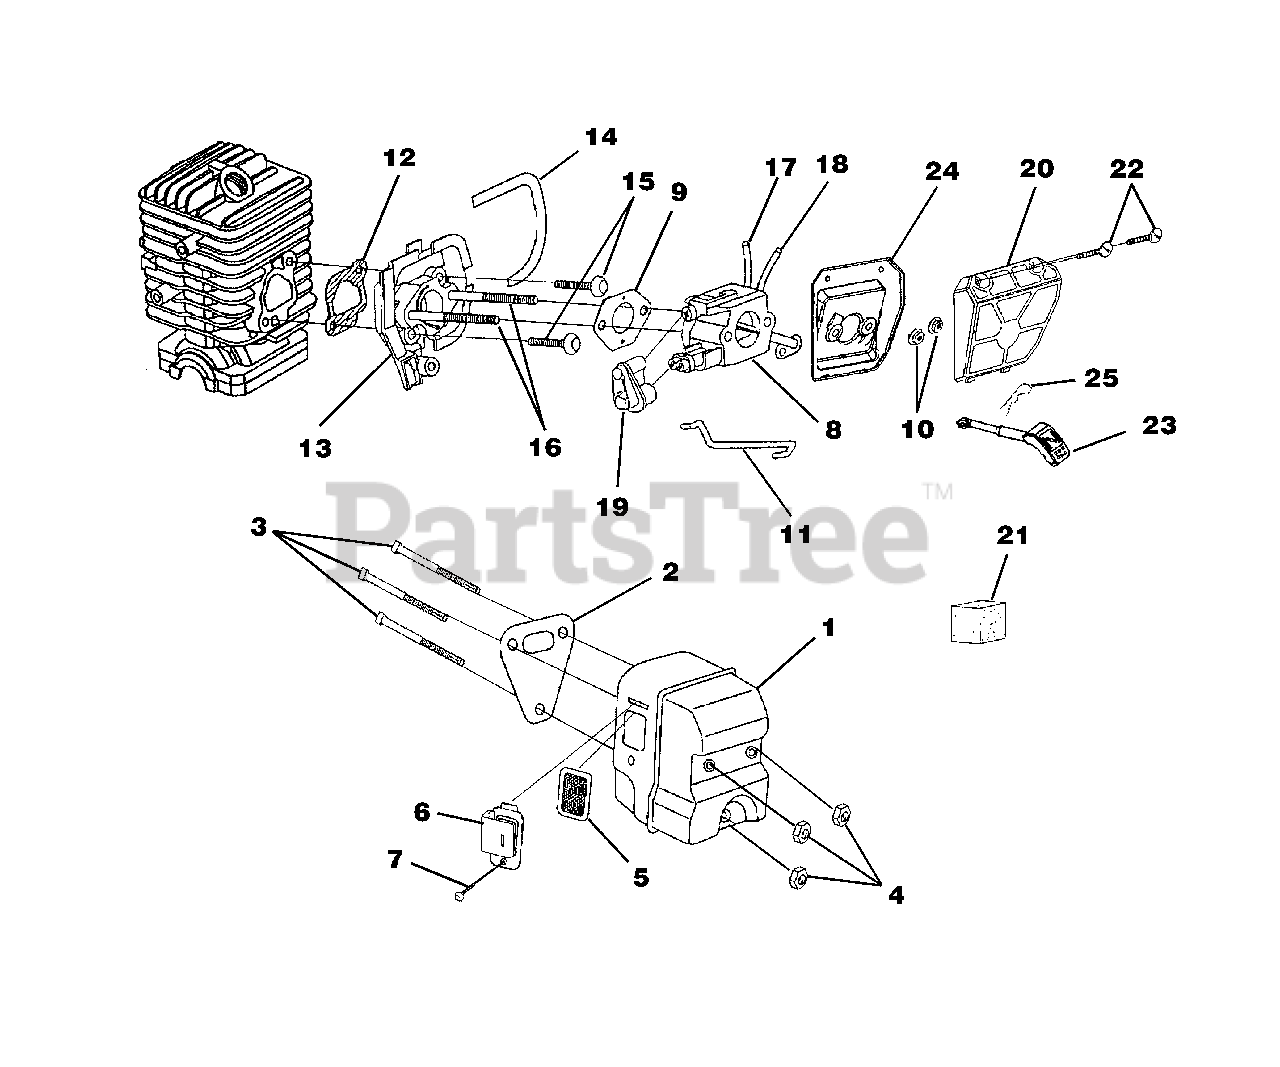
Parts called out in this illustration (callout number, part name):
1	Muffler Kit
2	Muffler Gasket
3	Screw-Square Hd.
4	Nut-Locking Hex (10-32)
5	Screen, Spark
6	Deflector, Muffler
7	Screw (8-32 x .312)
8	Carburetor Assembly
9	Carburetor Gasket
10	Flange Nut (10-24)
11	Throttle Wire
12	Gasket, Heat Dam
13	Heat Dam
14	Seal, Heat Dam
15	Screw, Truss Hd. Taptite (10-24 x 7/8")
16	Screw, Carburetor
17	Fuel Line (Tank to Carburetor 8 1/2")
18	Fuel Line (Carburetor to Purge Bulb 4")
19	Carburetor Grommet
20	Air Filter Cover
21	Pre Filter (In engine housing)
22	Screw-Slotted Pan Hd. (8-16 x 5/8")
23	Rod, Choke
24	Air Filter Plate
25	Spring Clip (Choke Rod)
